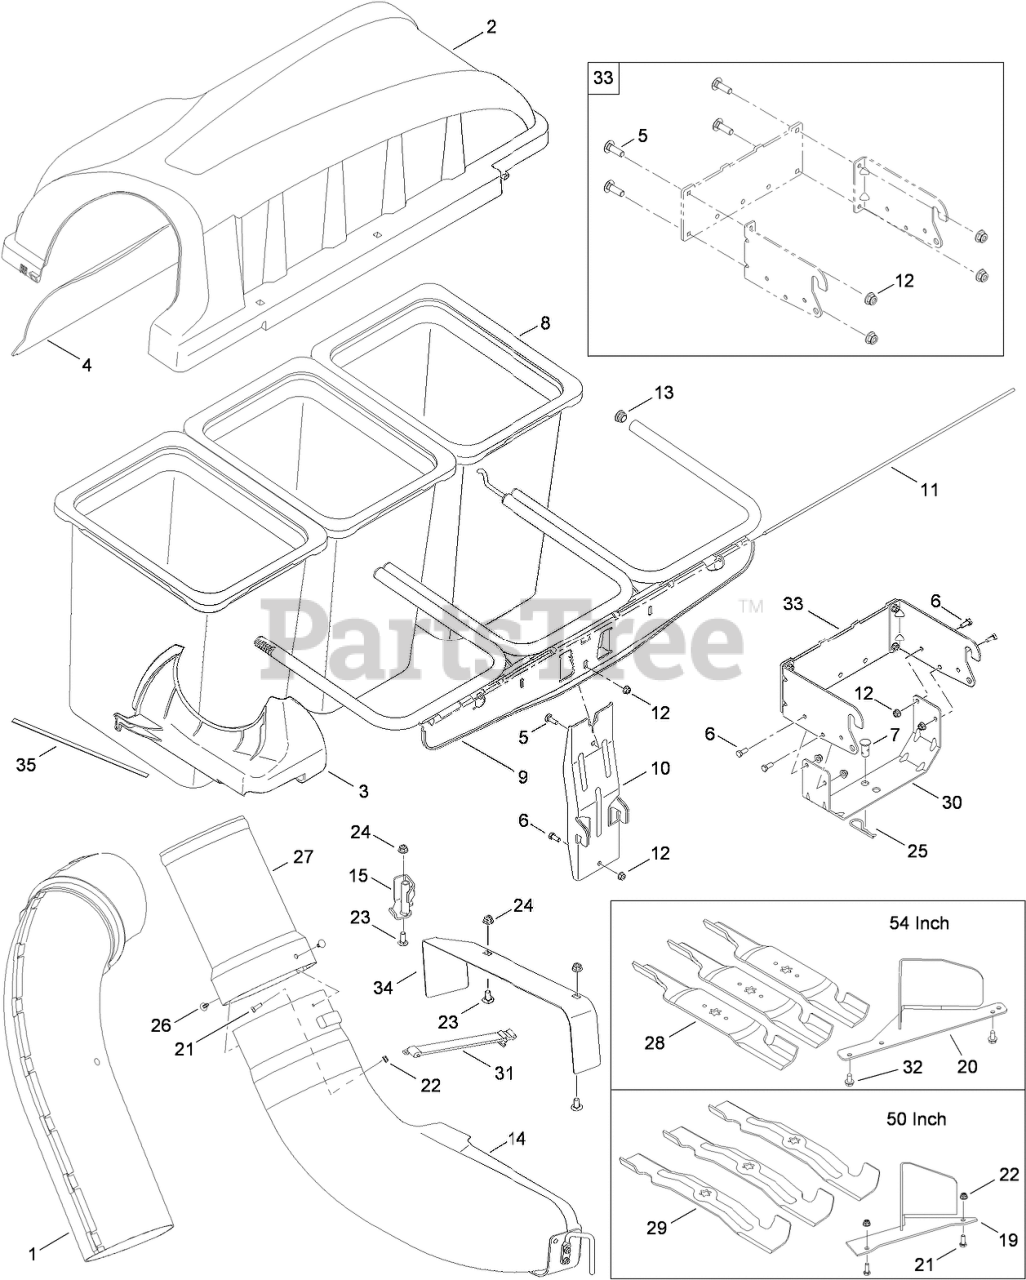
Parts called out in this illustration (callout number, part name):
1	UPPER CHUTE ASM
2	TRIPLE BAGGER COVER ASM
3	SUPPORT-CHUTE, UPPER
4	SCREEN-COVER, BAGGER
5	BOLT-CARR
6	SCREW-HH
7	PIN-CLEVIS
8	GRASS BAG ASM
9	TRIPLE BAG SUPPORT ASM
10	BRACKET-SUPPORT, VERTICAL
11	PIN-HINGE, COVER
12	NUT-LOCK, FLANGE
13	PLUG-END
14	ELBOW-CHUTE, DISCHARGE
15	BRACKET-STOP, CHUTE
19	Baffle-Deck
20	BAFFLE-DECK, 54 INCH
21	SCREW-HH
22	NUT-LOCK, FLANGE
23	BOLT-CARRIAGE
24	NUT-LOCK, FLANGE
25	CLIP-HAIRPIN
26	CLIP-RATCHET, FASTENER
27	ADAPTER-CHUTE, BAGGER
28	BLADE-EXTRA HI LIFT (18.50 INCH)
29	BLADE-BAGGING (STAR, 17.90 INCH)
30	SUPPORT-BRACKET, UNIVERSAL
31	STRAP-CHUTE
32	SCREW-TAP
33	HITCH BRACKET ASM
34	PLATE-CHUTE, DISCHARGE
35	FOAM STRIP-SELF ADHESIVE
